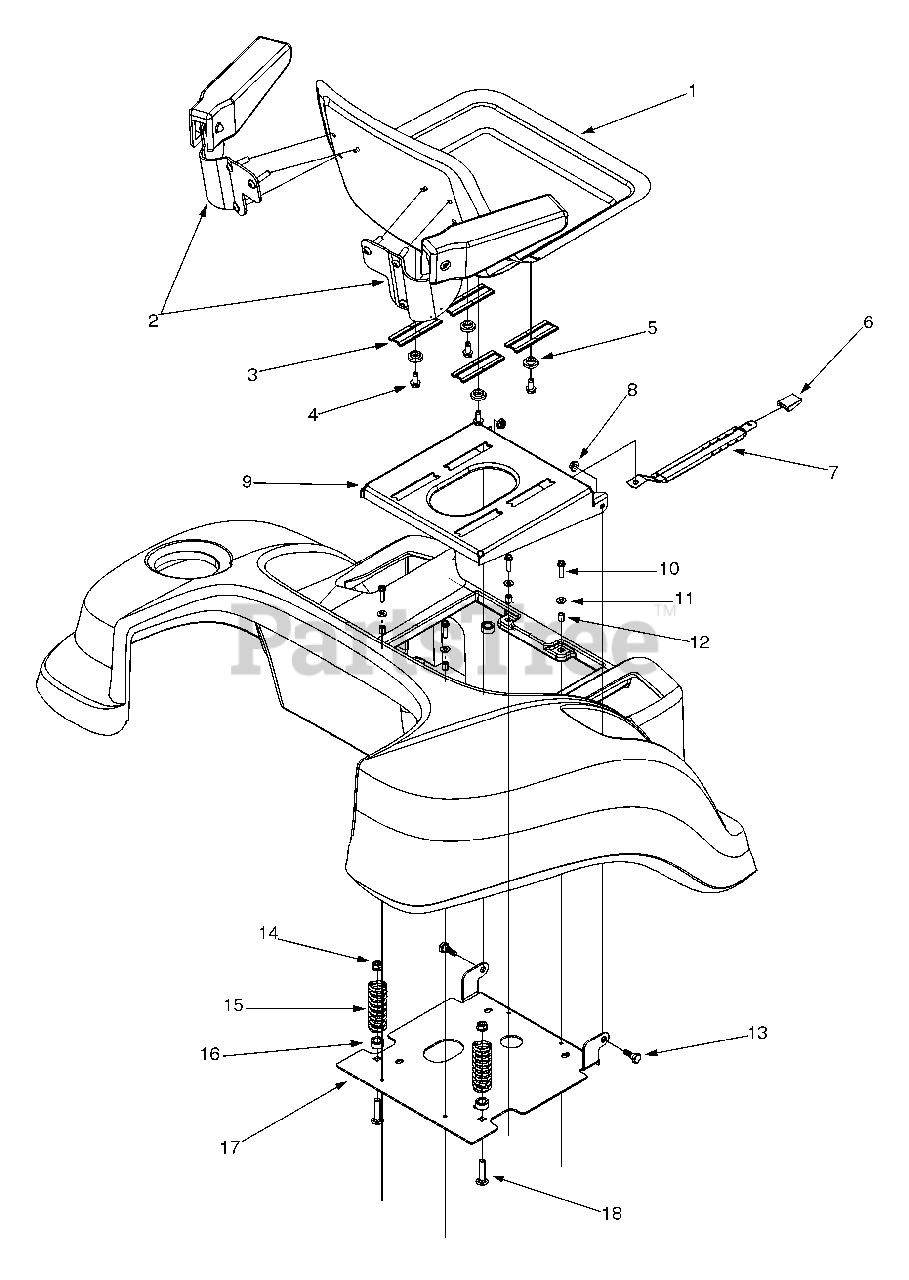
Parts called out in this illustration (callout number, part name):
1	Seat Ass'y
2	Seat Arm Ass'y
3	Seat Slide
4	Hex Washer Screw 5/16-16 x .750
5	Shoulder Spacer
6	Height Adjuster Knob
7	Spring Index
8	Flange Lock Nut 5/16-18
9	Seat Base Bracket Ass'y
10	Hex Washer Screw 1/4-20 x 1.0
11	Flat Washer .25 x .630
12	Spacer
13	Shoulder Screw
14	Flange Lock Nut 3/8-16
15	Compression Spring
16	Spacer
17	Seat Plate Ass'y
18	Hex Carriage Screw 3/8-16 x 1.75
